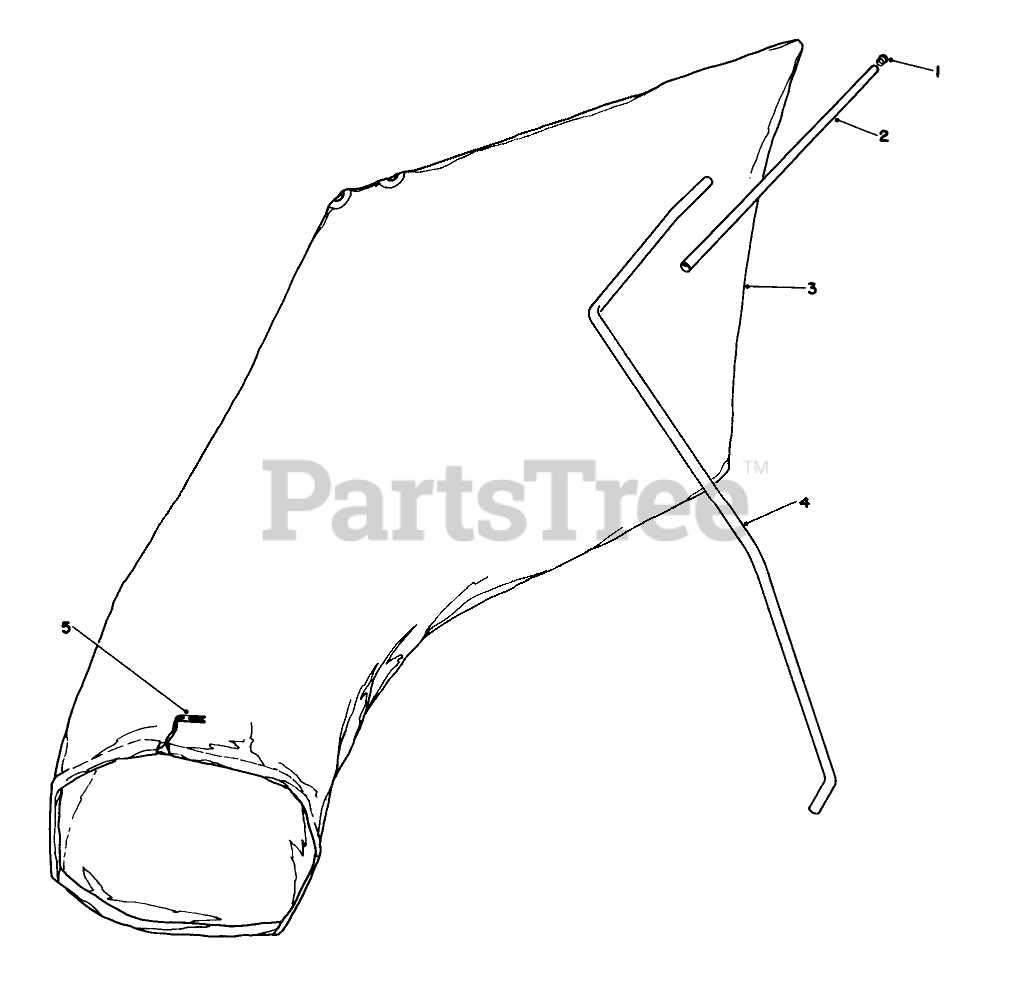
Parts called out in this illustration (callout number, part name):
2	BAG HANGER TUBE
3	Bag Assembly (Incl. Ref. #5)
4	HANGER ROD
5	BAG CORD FASTENER
